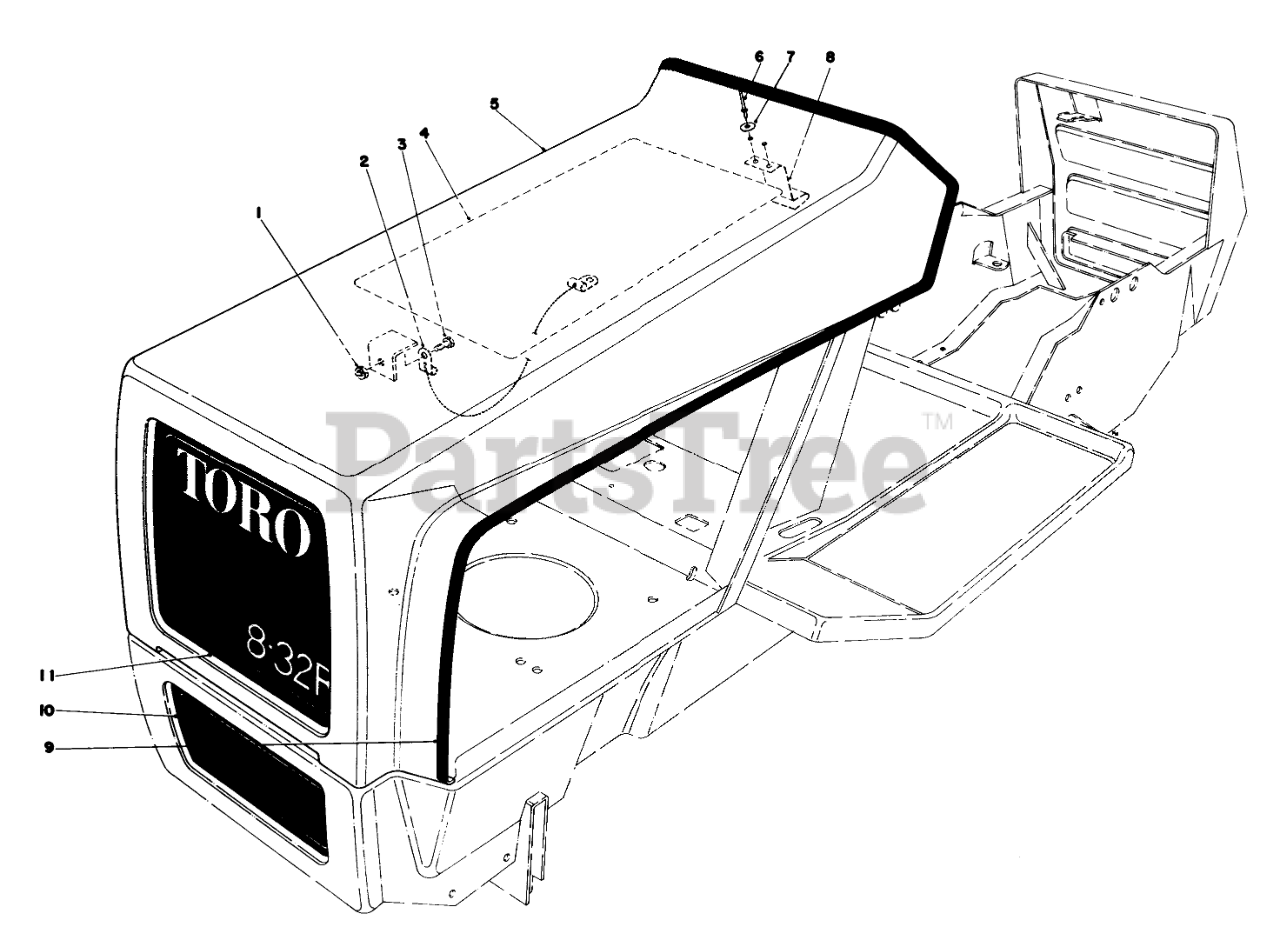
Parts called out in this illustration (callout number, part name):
1	NUT-LOCK, CONE
2	Lanyard-Hood
3	SCREW-HH
4	Decal-Service
6	RIVET-POP
7	WASHER-FLAT
8	Spring-Latch
9	Vinyl Trim
10	Decal-Frame
11	Decal-Hood
